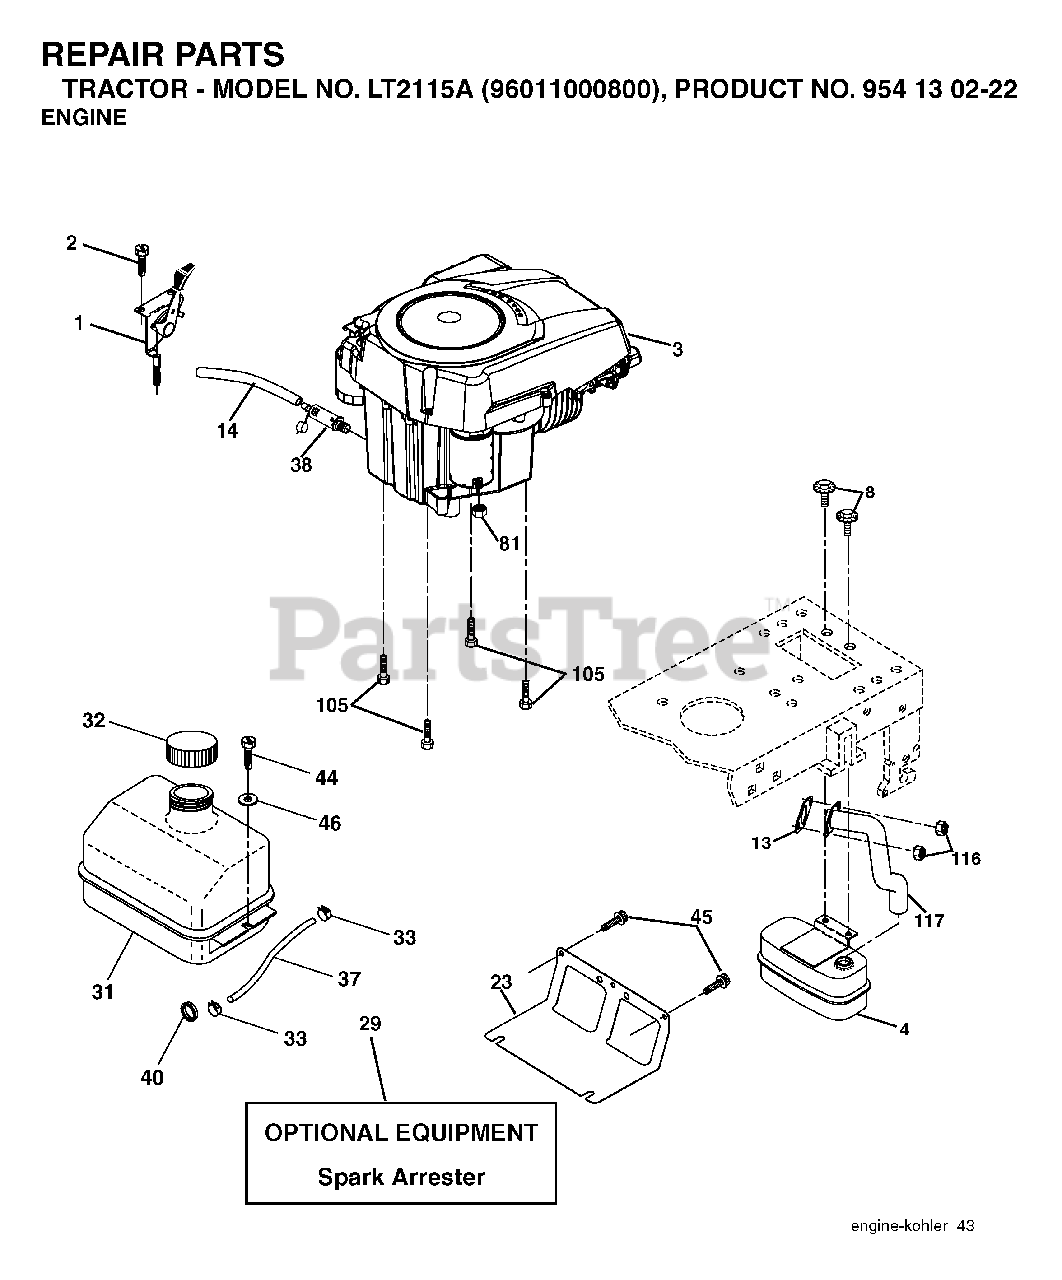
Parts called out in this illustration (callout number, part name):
1	CONTROL.THROTTLE.LT/YT
2	SCREW
4	MUFFLER.SINGLE.CYL.KOHL/B&S
8	BOLT, 5/16-18 X 1 3/4
13	GASKET ENGINE
14	TUBE, DRAIN OIL ASM.
23	SHEILD.BROWNING.DBR.GUARD
29	ARRESTER SPARK (OPTIONAL)
31	FUEL TANK
32	FUEL CAP
33	HOSE CLAMP
37	LINE.FUEL.20
38	PLUG DRAIN OIL EASY
40	GROMMET T
44	SCREW HEXWSHR 1/4-20X3/4
45	SCREW, 3/8-16X3/4
46	WASHER
81	NUT
105	SCREW 3/8-16X1
116	NUT.HEX.FLANGE.TOPLOCK
117	TUBE EXHAUST
